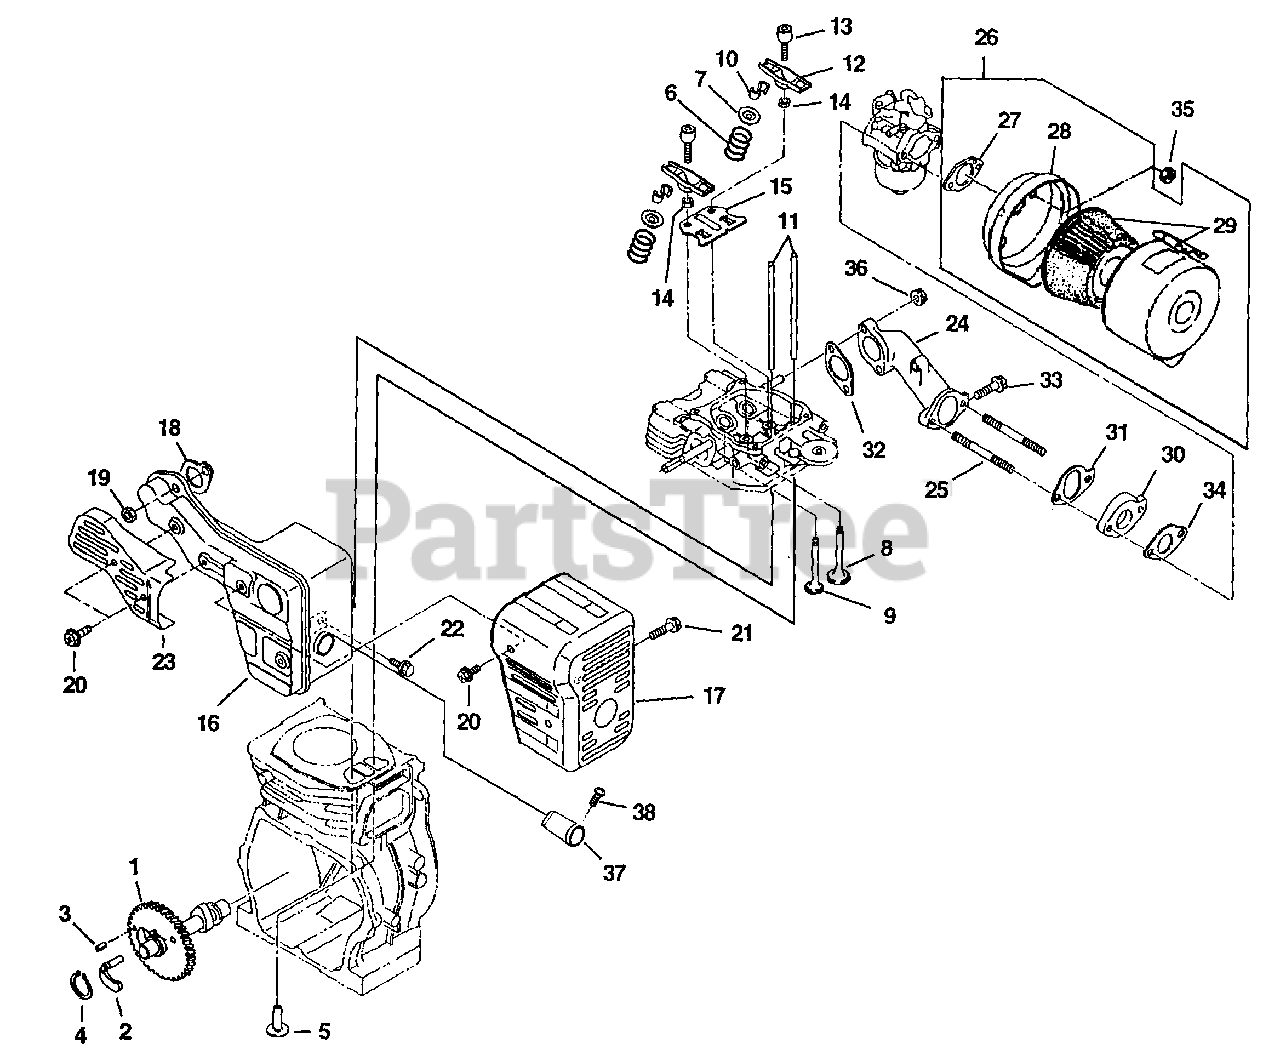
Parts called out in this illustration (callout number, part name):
1	Camshaft
2	Release lever
3	Spring pin
4	Snap ring
6	Valve spring
7	Spring retainer
8	Intake valve
9	Exhaust valve
10	Collet valve
11	Push rod
12	Rocker arm
13	Pivot bolt
15	Guide plate
17	Muffler cover
18	Muffler gasket
20	Tapping bolt M8
21	Tapping bolt M8
22	Flange bolt M6 X 1.0 X 12L
23	Exhaust pipe cover
24	Intake pipe
26	Air cleaner assy
28	Plate
30	Insulator
31	Insulator gasket
32	Insulator gasket
33	Flange bolt
34	Insulator gasket
35	Nut & washer M6
36	Flange nut
37	Spark arrestor
38	Tapping screw
